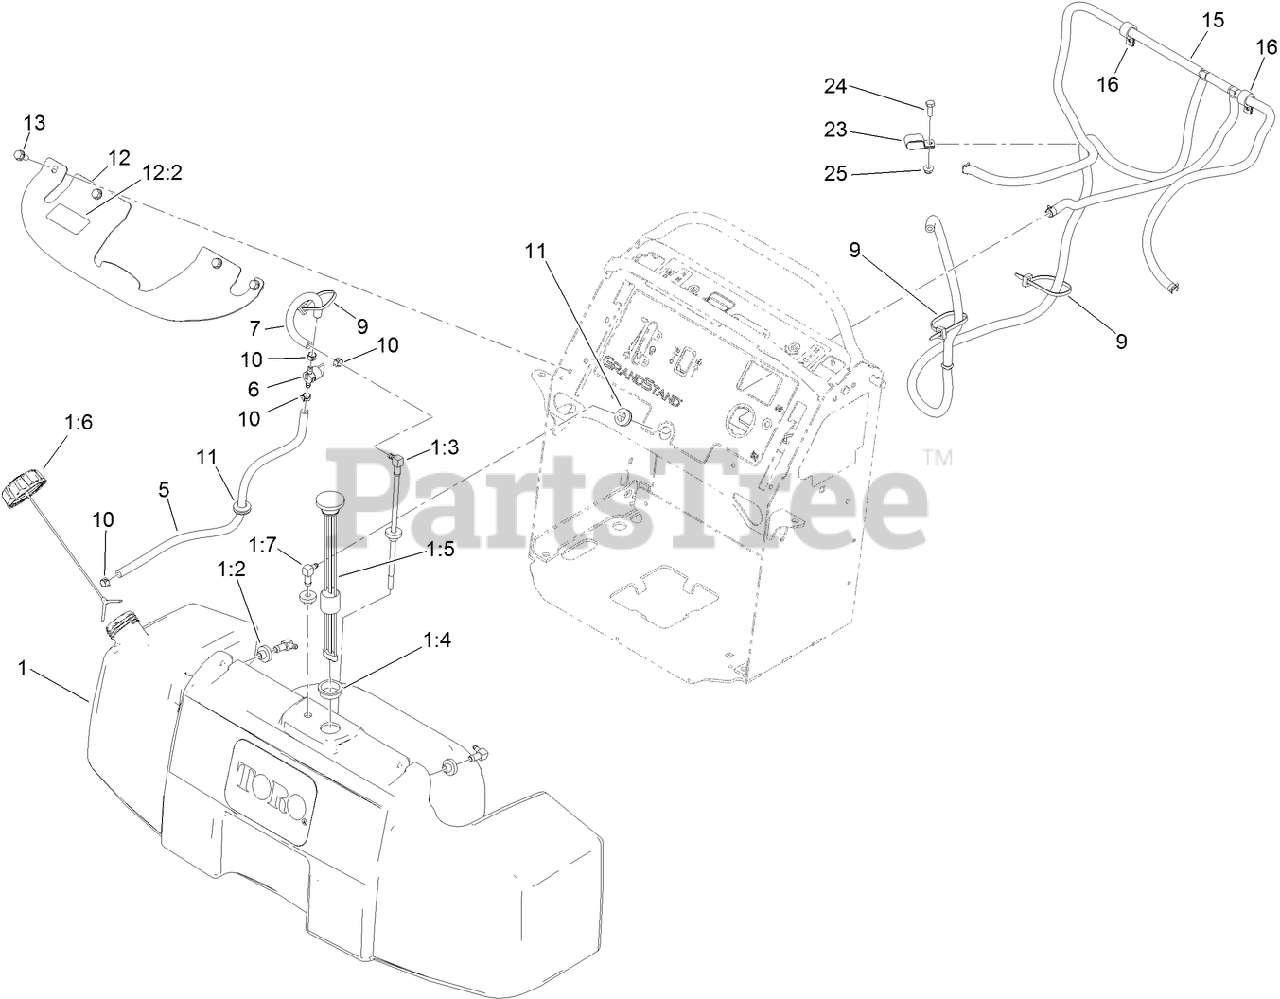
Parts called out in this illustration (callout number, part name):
1	TANK ASM
1:2	BUSHING
1:3	FITTING-FUEL, SCREEN TUBE
1:4	GROMMET
1:5	GUAGE-FUEL
1:6	CAP-FUEL
1:7	ELBOW-90 DEG
5	HOSE-FUEL
6	VALVE-FUEL
7	HOSE-FUEL
9	TIE-CABLE
10	CLAMP-HOSE
11	GROMMET
12	BRACKET-TANK
12:2	DECAL-FILL, FUEL
13	SCREW-HWHTF
15	VENT HOSE ASM
16	CLAMP-CABLE
23	CLAMP-TUBE, DOUBLE
24	SCREW-HH
25	NUT-HF
